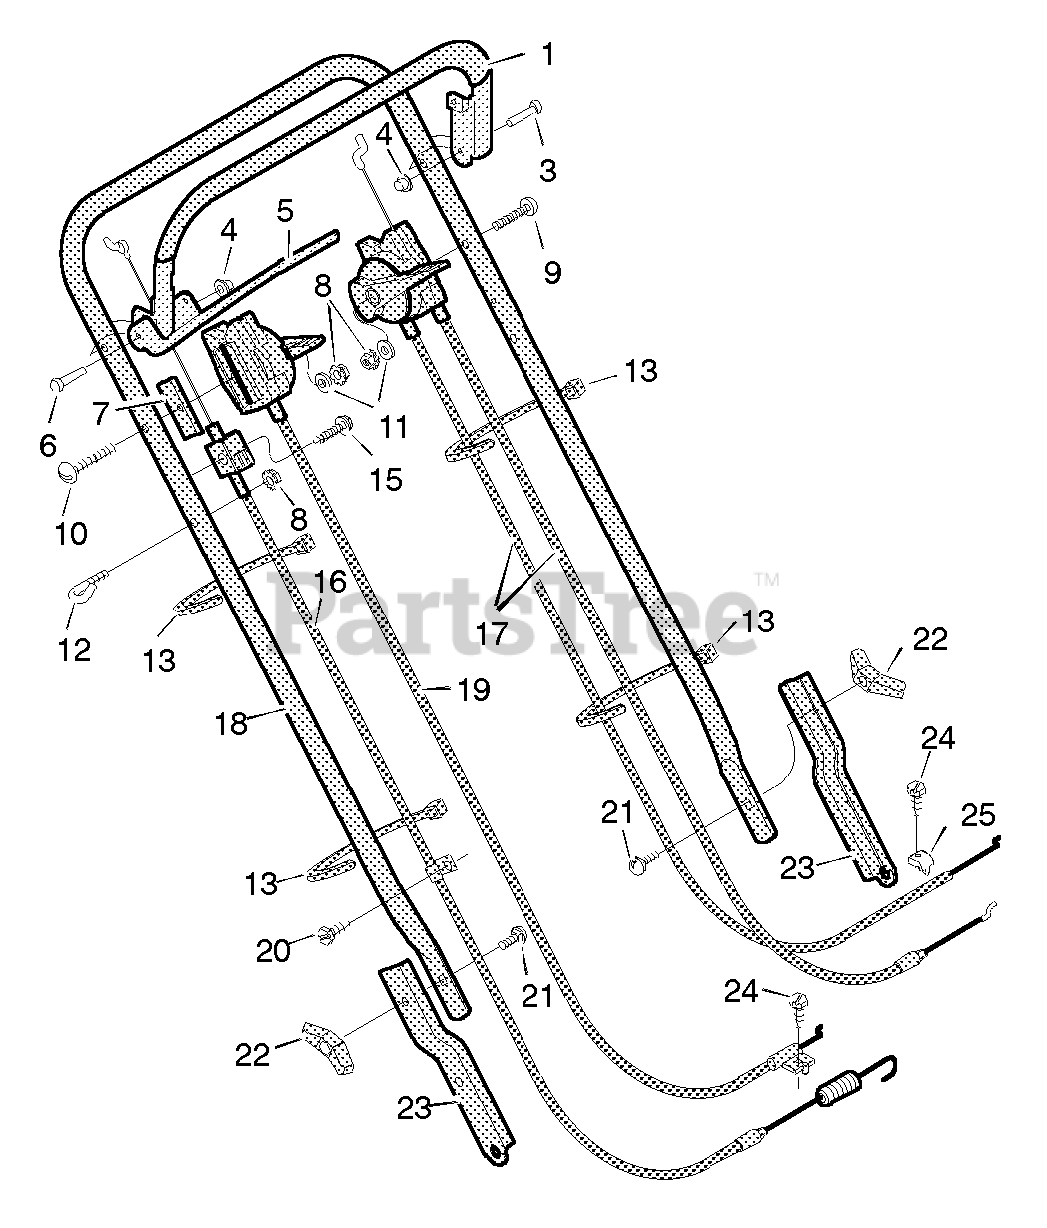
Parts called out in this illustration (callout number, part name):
1	Stop Lever
4	Push On Cap
5	Lever, Drive
7	Spacer
8	Locknut
12	GUIDE, ROPE
13	Fastener, Cable
16	Cable, Drive
17	Throttle and Stop Cable (Briggs 5.5 HP)
18	Handle (Black)
19	Control, Speed
21	Bolt, Carriage
23	Bracket, Handle (Black)
